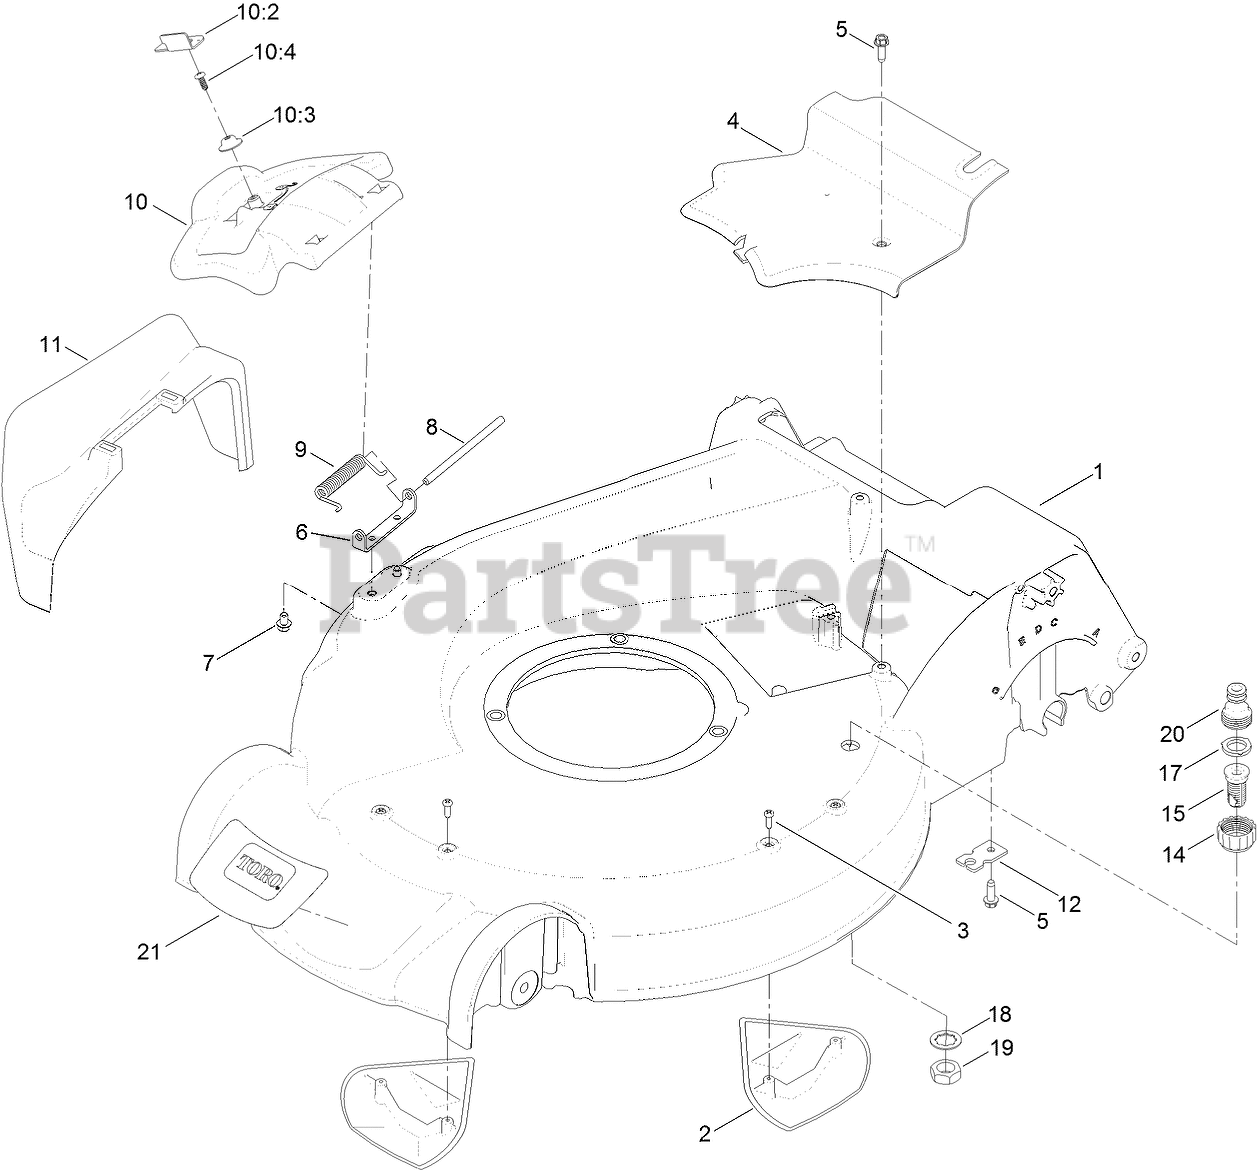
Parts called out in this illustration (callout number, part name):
1	HOUSING ASM
2	KICKER-HOUSING
3	SCREW-PPH
4	COVER-BELT
5	SCREW-HWHTF
6	BRACKET-COVER
7	SCREW-HWH
8	ROD-COVER
9	SPRING-TORSION
10	DISCHARGE DOOR ASM
10:2	LATCH-DOOR
10:3	CAP-DOOR
10:4	SCREW-PLASTITE
11	CHUTE-DISCHARGE, SIDE
12	BRACKET-CABLE, TRACTION
14	COUPLING-HOSE, WASHOUT PORT
15	PORT-WASHOUT
17	WASHER-SEAL, WASHOUT PORT
18	WASHER-TOOTH, INTERNAL
19	NUT-JAM
20	ADAPTER-CONNECT, QUICK
21	DECAL-DECK
